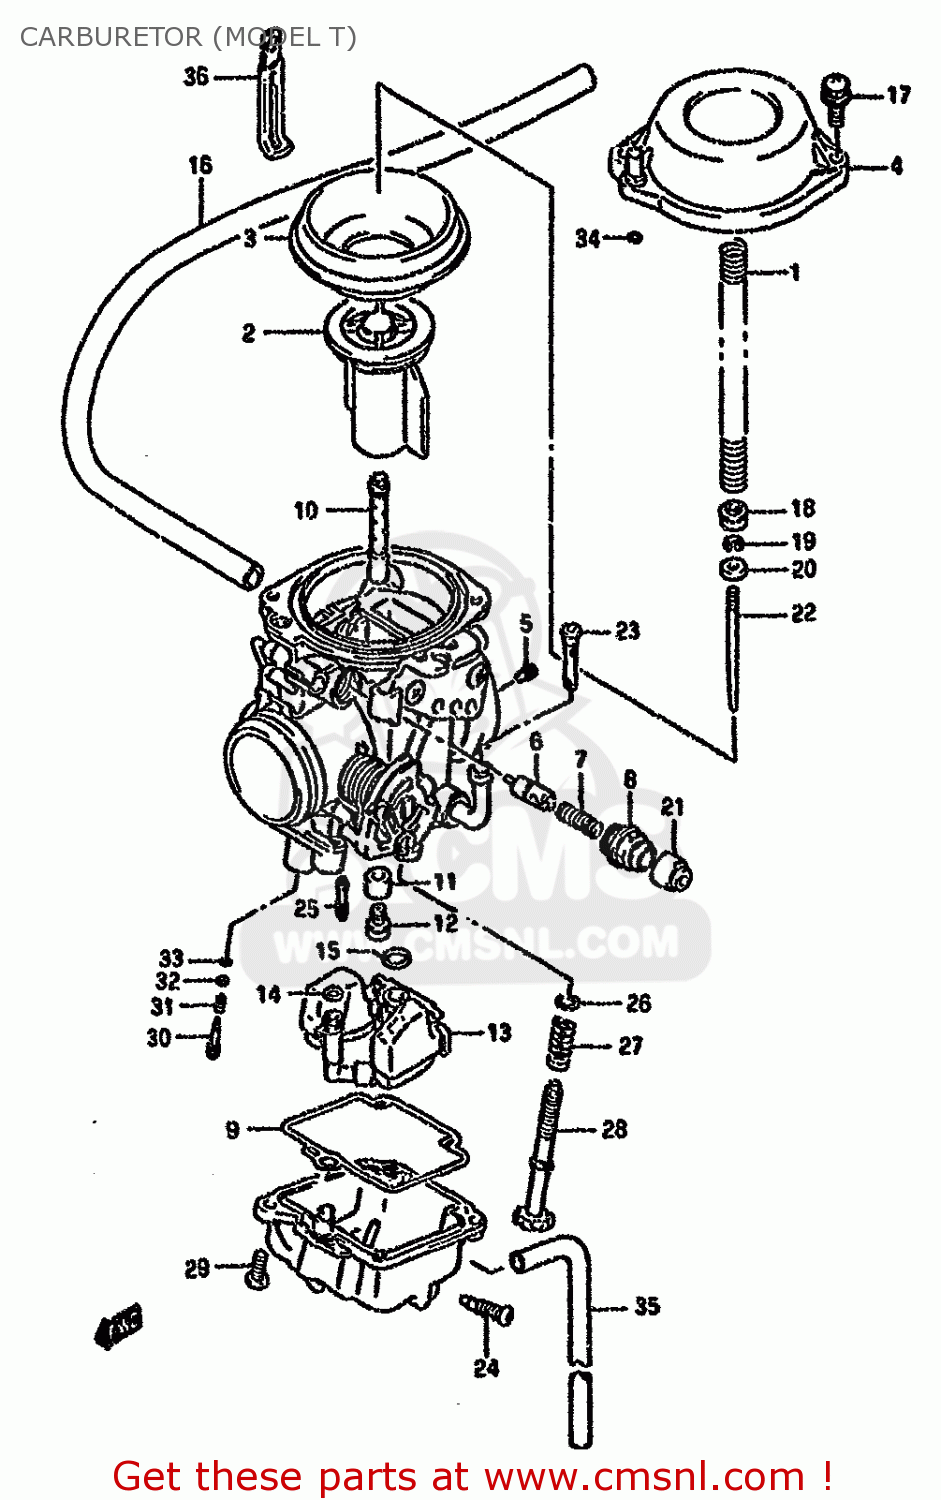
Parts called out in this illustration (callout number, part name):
1	SPRING
2	VALVE,PISTON
3	DIAPHRAGM
4	COVER,DIAPHRAGM
5	JET,AIR
6	PLUNGER
7	SPRING
8	HOLDER,GUIDE
9	GASKET,FLOAT CHAMBER (NAS)
10	JET,NEEDLE,X-9
11	RING
12	JET,MAIN(140)
13	FLOAT/NEEDLE VALVE ASSY
14	O RING
15	O-RING,NEEDLE VALVE
16	HOSE(6.5X11.5X600)
17	SCREW
18	RING
19	CLIP,NEEDLE
20	RING
21	CAP
22	NEEDLE,JET
23	FILTER
24	SCREW,DRAIN
25	JET,PILOT(50)
26	WASHER
27	SPRING
28	ADJUSTER
29	SCREW(5X14)
30	SCREW,PILOT
31	SPRING
32	WASHER
33	O RING,PILOT AIR SCREW
34	O RING
35	HOSE
36	SPRING
37	WASHER
38	O RING,PILOT AIR SCREW
39	SEAL
40	GASKET,THROTTLE SHAFT (NAS)
41	E RING
42	O RING
43	HOSE
44	CLAMP
